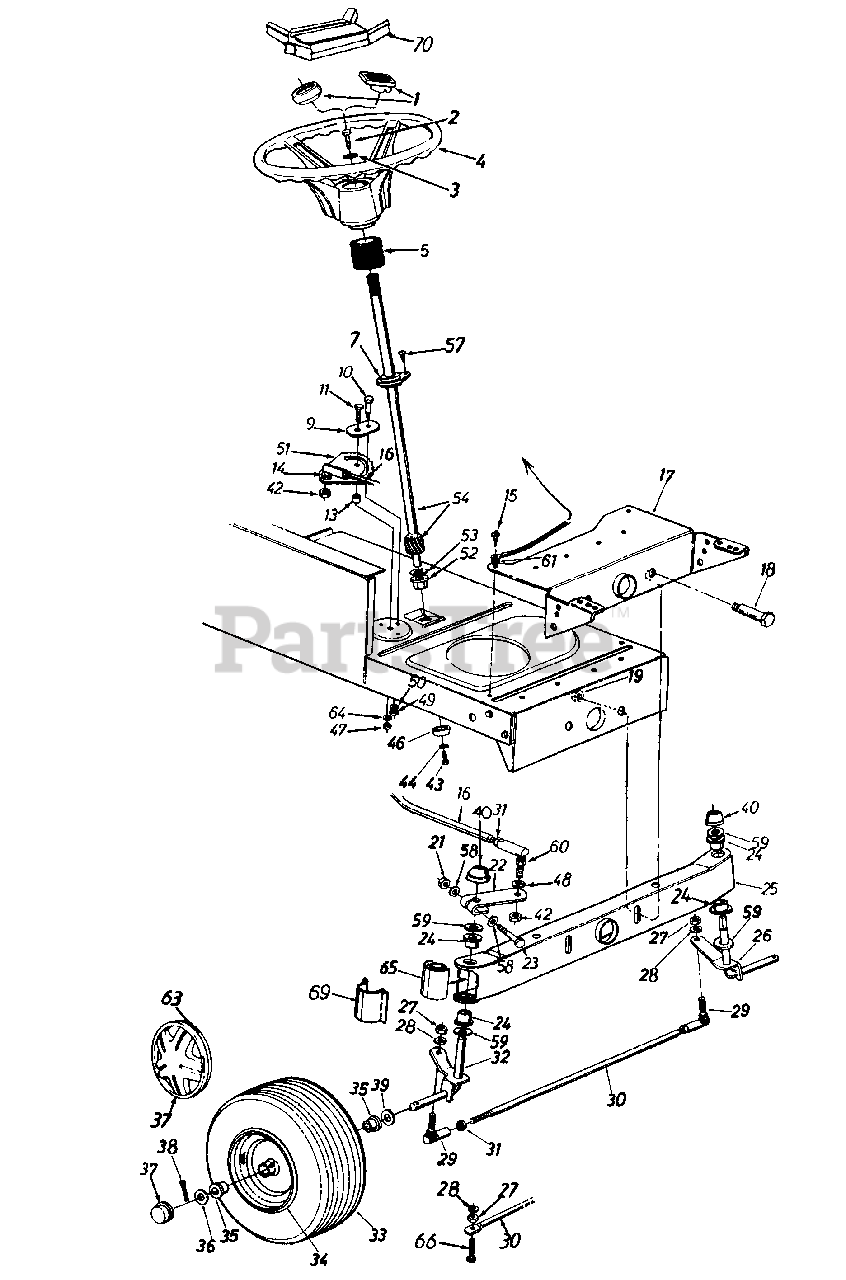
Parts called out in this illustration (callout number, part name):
1	Steering Wheel Cap
1	Steering Wheel Cap (Sq.- MTD)
1	Steering Wheel Cap (Square - No Logo)
2	Hex Bolt 5/16-18 x 1" Lg.
3	Belleville Wash. .345" I.D.
4	Steering Wheel (3 Spoke)
4	Steering Wheel (4 Spoke)
5	Steering Bellow - 4.5"
5	Steering Bellow - 9"
5	Steering Bellow - 3.25"
7	Flange Bearing .628" I.D. x 1.36 O.D.
9	Retainer Plate
10	Shoulder Bolt .437" Dia. x .35 Lg. 5/16-18 Thd.
11	Hex Bolt 3/8-24 x 1.0" Lg. (Gr. 5)
13	Spacer .380" I.D. x .625" O.D. x .227
14	L-Wash. 3/8" I.D. (H.D.)
15	Hex Wash. Hd. Self-Tap Scr.
16	Drag Link Kit
16	Steering Drag Link
16	Steering Drag Link 7/16-20
18	Shoulder Bolt .498" Dia. x 2.04 Lg. 3/8-16 Thd.
19	Flanged L- Nut 3/8-16 Thd.
21	Hex L-Nut 5/16-24 Thd.
22	Steering Arm Front Axle
23	Hex Bolt 5/16-24 x 2.00" Lg. (Gr.5)
24	Hex Flg. Brg. .632 I.D.
25	Pivot Bar Ass'y.
26	Front Axle Ass'y - L.H. 15" x 6" (Round Shoulder)
27	Hex Nut 3/8-24 Thd.
28	L-Wash. 3/8" I.D.
29	Ball Joint 3/8-24 Thd.
30	Tie Rod (Adjustable)
30	Tie Rod (Non-Adjustable)
31	Hex Jam Nut 3/8-24 Thd.
32	Front Axle Ass'y - R.H. 15" x 6" (Round Shoulder)
33	Wheel Ass'y Comp., 15" x 6" (Round Shoulder)
34	Rim Only, 15" x 6" (Round Shoulder)
35	Bearing, 15" x 6" (Round Shoulder)
36	Fl-Wash .635 I.D. x 1.59" O.D.
37	Front Wheel Hub Cap
37	Spoked Hub Cap (Yellow)
37	Spoked Hub Cap (Gray)
37	Spoked Hub Cap (Beige)
38	Cotter Pin 1/8" Dia. x 1.25"
39	Fl-Wash .640" I.D. x 1 24" O.D.
40	Push Cap 5/8" Dia. Rod
42	Hex Jam Nut 3/8-24 Thd.
43	Hex Patch Bolt 5/16-18 x .62"
44	L-Wash. 5/16" I D.
45	Fl-Wash. .33" I.D. x 1.25" 0 D
47	Hex Cent L-Nut 3/8-24 Thd.
48	L-Wash. 3/8" I.D.
49	Hex Cent L-Nut 5/16-18 Thd.
50	L-Wash. 5/16" I.D.
51	Steering Gear Segment
52	Hex Flg. Brg. .634 I.D.
53	Fl-Wash. (Hardened)
54	Steering Shaft
57	Oval Hd. Cr - Sunk Scr. #10 x 5/8" Lg.
58	Wave-Wash .32" I.D. x .62" O.D.
59	Fl-Wash. (Hardened)
60	Drag Link Ball Joint 7/16-20
60	Ball Joint Assembly
61	Ext. L-Wash. 5/16" I.D.
63	Spring Clip
64	Bell-Wash. .39" I.D. x 1.38" O.D.
65	Pivot Bar End Cap
66	Hex Bolt 3/8-24 x 1.5" Lg. (Gr 5)
69	Axle Cap
70	Steering Wheel Insert
